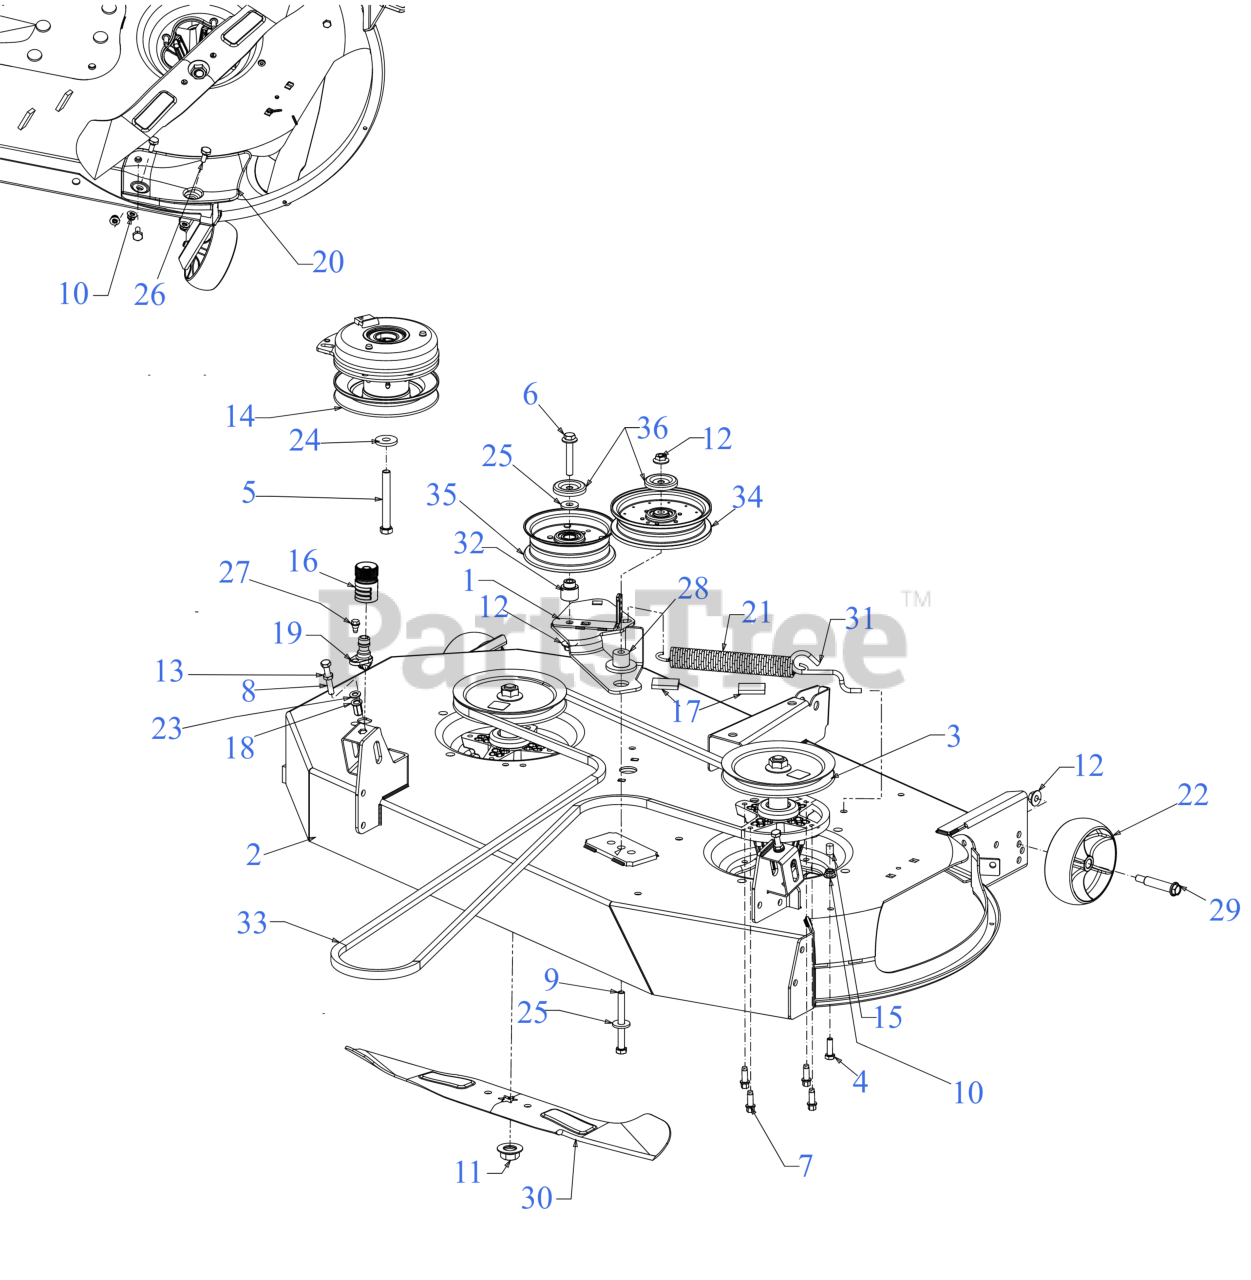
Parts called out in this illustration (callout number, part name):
1	BRACKET ASSEMBLY-DECK IDLER
2	46" FAB DECK SHELL
3	SPINDLE ASSEMBLY
3	Cub Cadet 46" SPINDLE ASSEMBLY (05078A)
4	SCREW 5/16-18 x 1.0 GR5
5	SCREW 7/16-20 x 3.5 GR5
6	SCREW 3/8-16 x 2.25 GR5
7	SCREW 5/16-18 x .875
8	SCREW-FULL THREAD 5/16-18 GR5
9	SCREW 3/8-16 x 3.50 GR5
10	FLANGE LOCK NUT 5/16-18
12	FLANGE LOCK NUT
14	ELECTRIC PTO CLUTCH
16	WATER NOZZLE ADAPTER
17	FOAM TAPE .75" WIDE x .25" THICK
18	NUT RIVET 5/16-18
19	DECK WASH NOZZLE
20	DISCHARGE BAFFLE
21	EXTENSION SPRING
22	DECK WHEEL (5.0 DIA x 1.875)
23	FLAT WASHER
24	FLAT WASHER .445 x 1.248 x .170
25	FLAT WASHER .406ID X1.0 OD
26	SHOULDER SCREW
27	SHOULDER SCREW 1/4-20 x .50
28	SHOULDER SPACER
29	SHOULDER BOLT (.50 X 2.0 x 3/8 -16)
30	23.25" BLADE (HIGH LIFT)
30	Cub Cadet 46" BLADE SET
30	Genuine Factory Parts 46" HI LIFT BLADE SET
31	DECK SPRING HOOK
32	SHOULDER SPACER
33	V-BELT A SEC x 120.8
33	Cub Cadet 46" RZT DECK BELT
33	Troy-Bilt 46" RZT DECK BELT
34	FLAT IDLER PULLEY
35	IDLER PULLEY 4.50" DIA
36	IDLER PULLEY CAP
